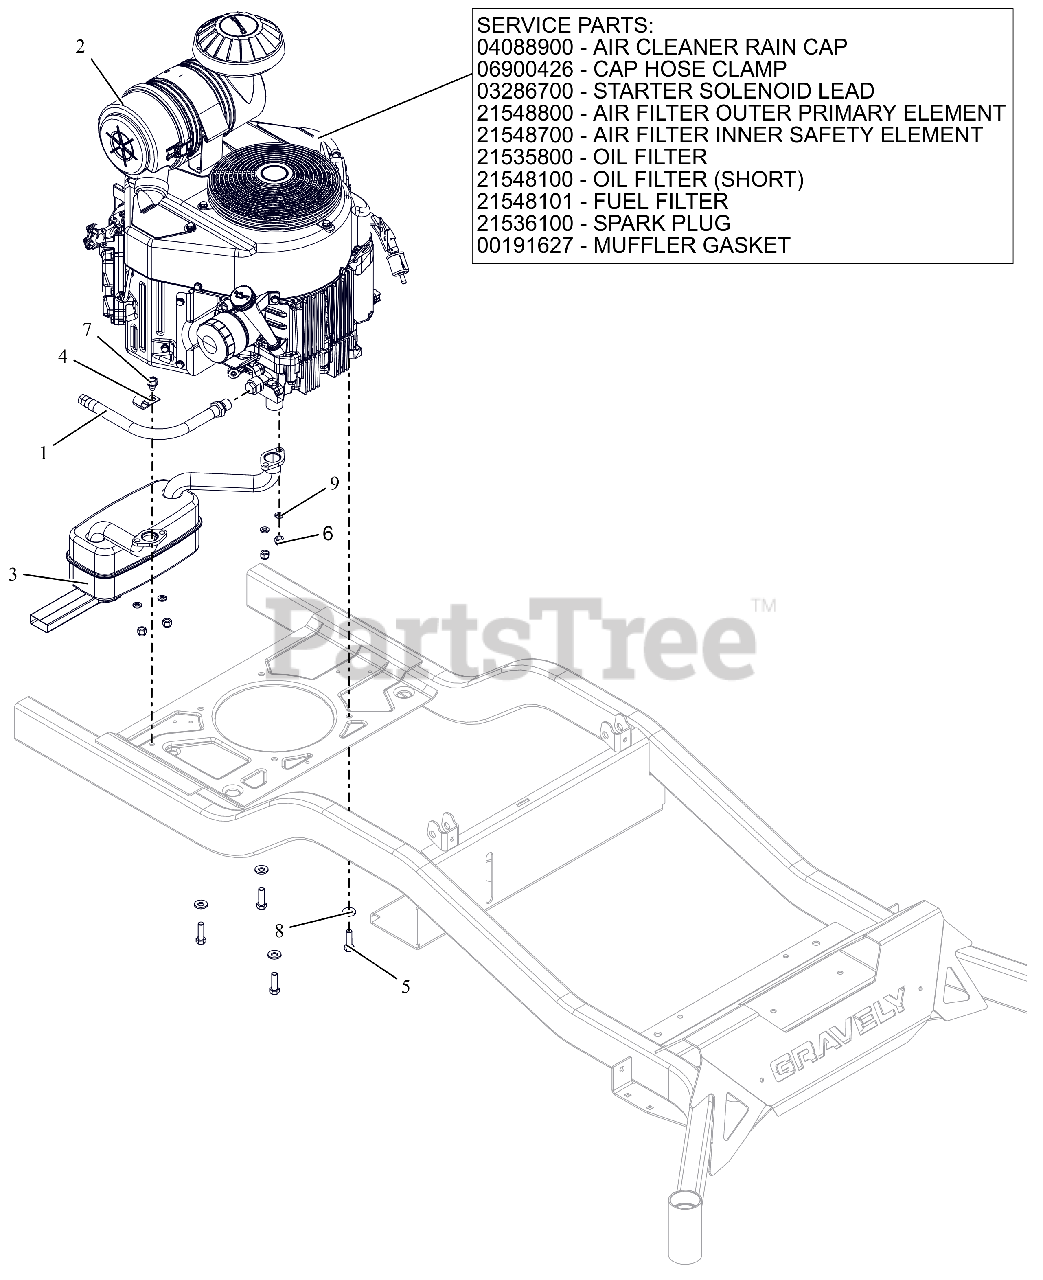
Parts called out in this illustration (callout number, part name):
1	HOSE, OIL DRAIN
2	ENGINE, KAWASAKI FX730
2	CAP, KAW 11065-7025
2	CLAMP, HOSE #36 SS 1.813-2.75
2	LEAD - STARTER SOLENOID
2	FILTER, OUTER
2	FILTER, INNER - KAW
2	FILTER,OIL - KAW
2	OIL FILTER, KAWASAKI FR
2	FUEL FILTER-KAWASAKI FR
2	PLUG, SPARK
2	GASKET, MUFFLER S/O
3	MUFFLER, KAWASAKI
5	BLT, HEX .38-16X1.25 G5 ZCC NT
6	NUT,NYL M8-1.25 G8.8 ZCC
7	SCR,TAP .375-16X.50 HWH TR ZCC
8	WASHER, 3/8" SPRING DISC
9	WSHR,LK-REG .312X.078 ZCC
